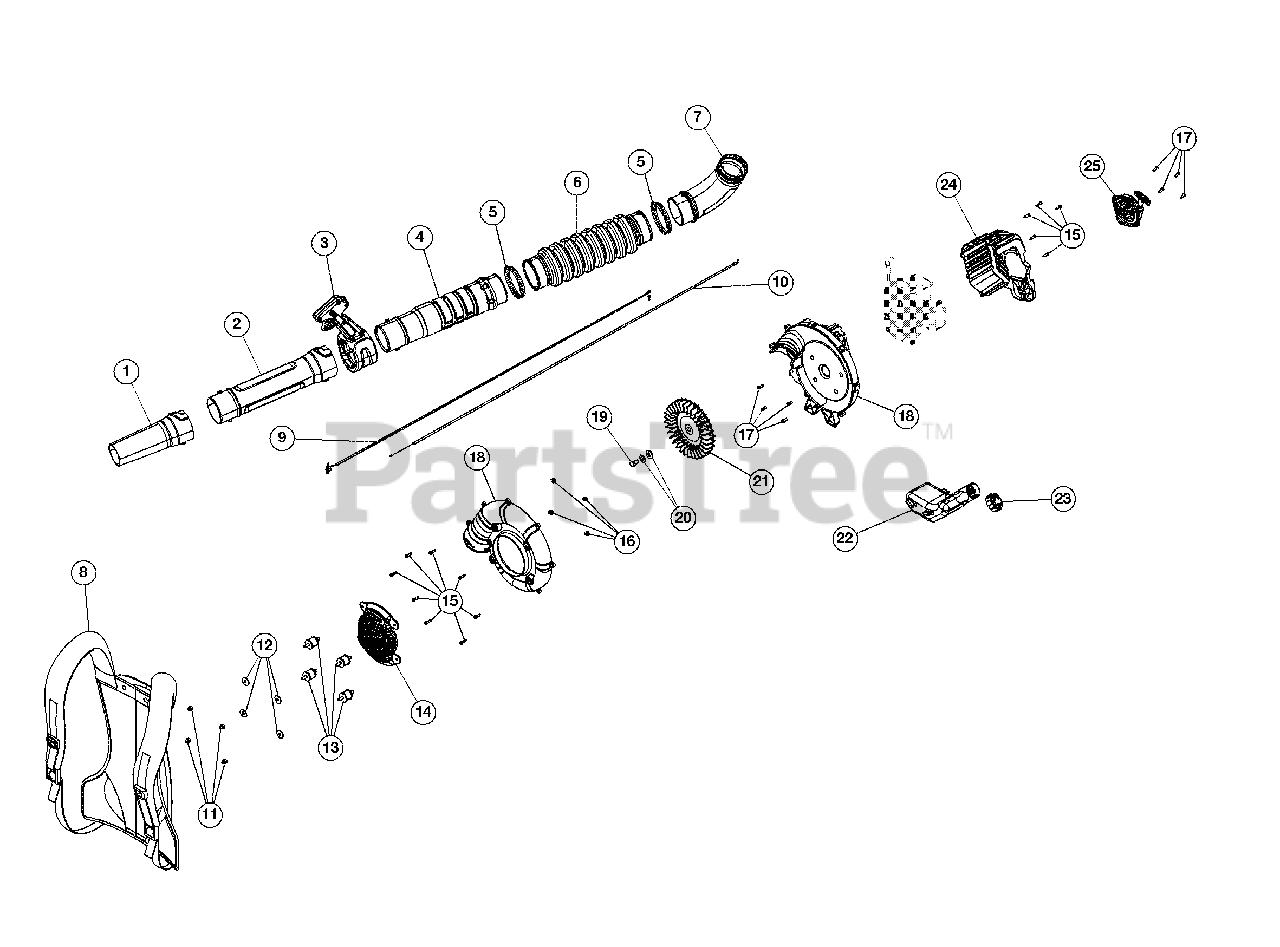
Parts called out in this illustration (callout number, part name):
1	Nozzle
2	Lower Blower Tube
3	Throttle Grip Assembly
4	Upper Blower Tube
6	Flex Tube
8	Harness
9	Lead Wire
10	Throttle Cable
11	Nut
12	Washer
13	Insulator Mount
14	Intake Cover
17	Screw
18	Impeller Housing Assembly (Incl. 13-17)
20	Impeller Hardware (Incl. 19)
21	Impeller (Incl. 19 & 20)
22	Fuel Tank Assembly (Incl. 23)
23	Fuel Cap
24	Housing Assembly (Incl. 15)
25	Starter Assembly (Incl. 17)
